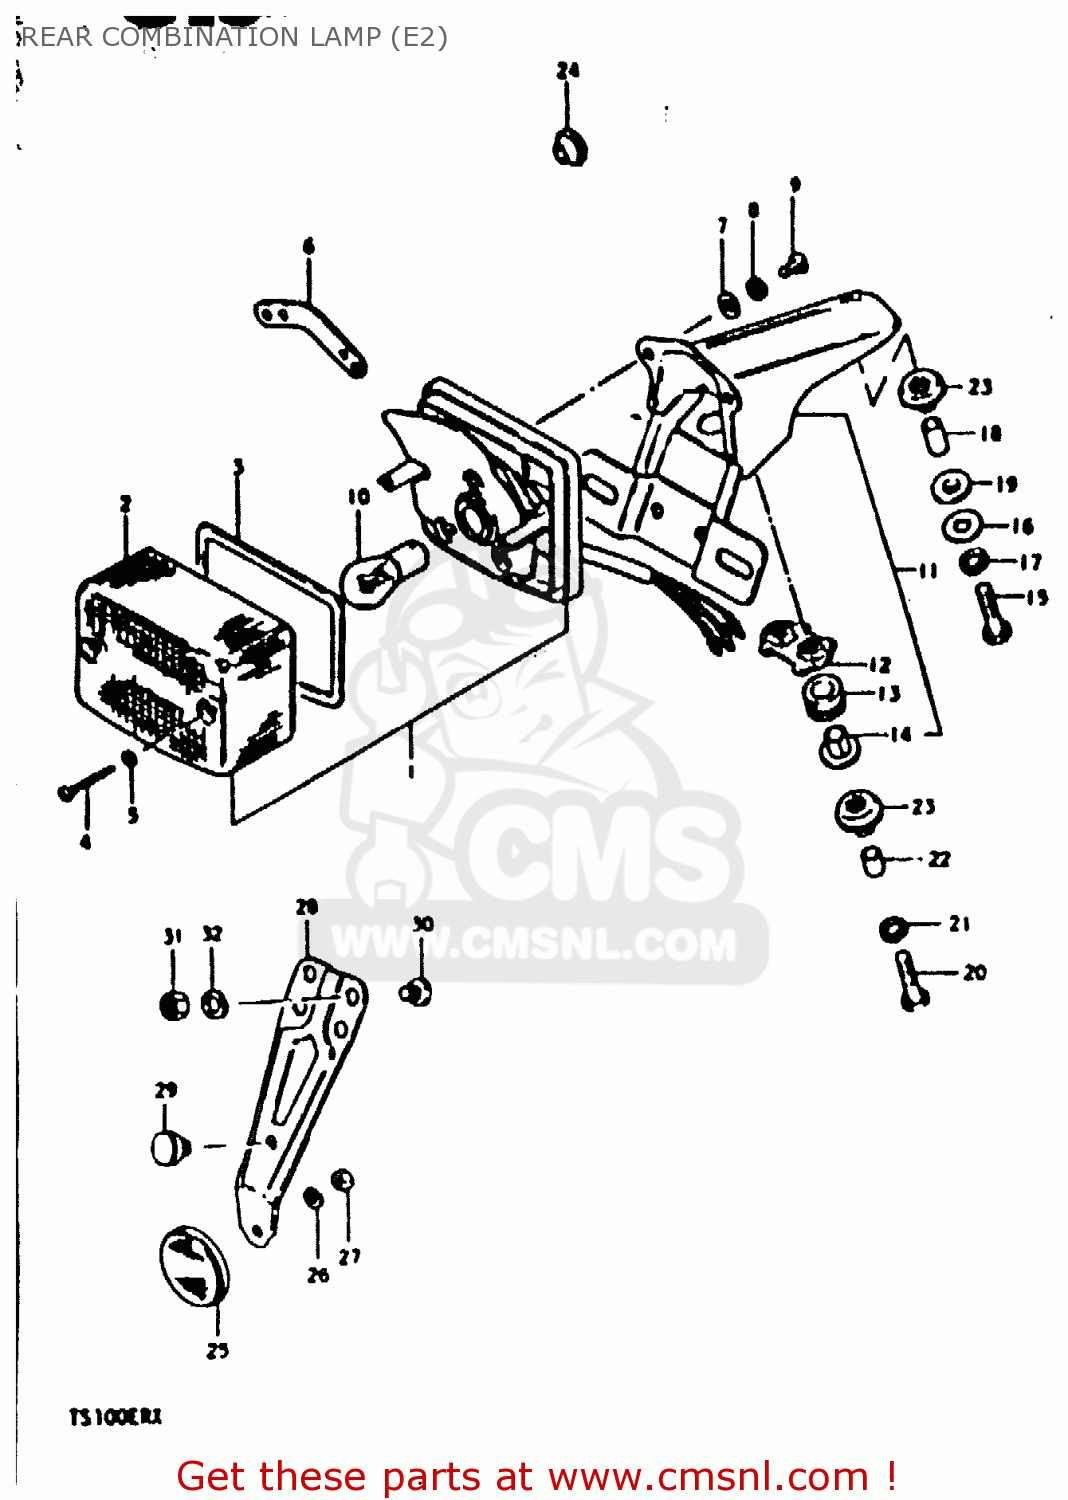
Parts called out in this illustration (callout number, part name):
1	LAMP UNIT, TAIL
2	LENS
3	GASKET (NAS)
4	BOLT
5	GASKET (NAS)
6	PLATE,REAR COMBINATION LAMP
7	WASHER
8	LOCK WASHER
9	SCREW
10	BULB (6V,21/5W)
11	BRACKET ASSY
12	PLATE
13	CUSHION
14	SPACER
15	BOLT
16	WASHER (6.5X20X1.2)
17	LOCK WASHER
18	SPACER
19	CUSHION
20	BOLT 6X40
21	LOCK WASHER
22	SPACER (6.8X10X11.5)
23	CUSHION
24	GROMMET
25	REFLEX REFLECTOR,RR
26	LOCK WASHER
27	NUT
28	BRACKET
29	CUSHION
30	SCREW
31	NUT
32	LOCK WASHER
